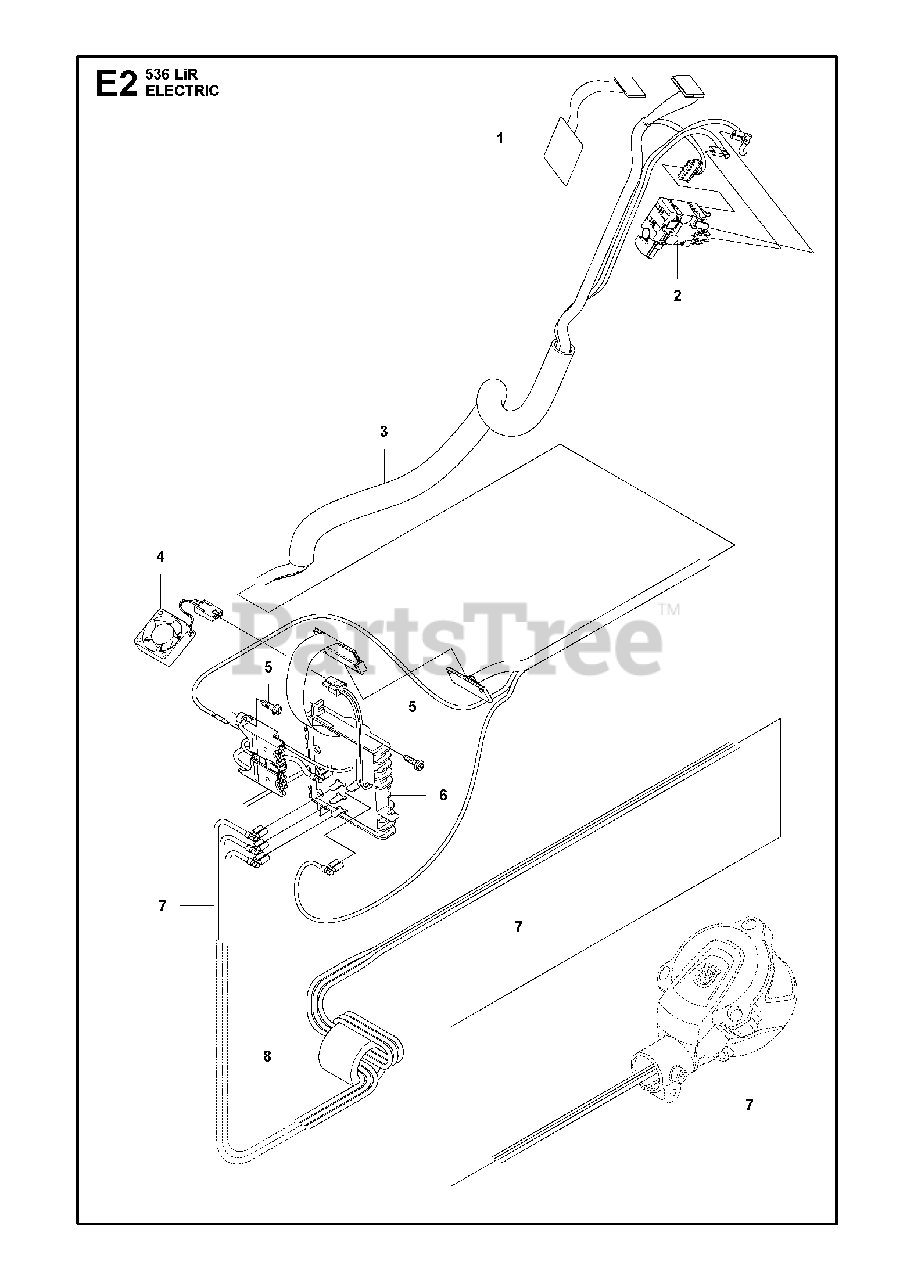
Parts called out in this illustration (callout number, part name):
2	TRIGGER SWITCH
7	MOTOR ASSY
8	FERRITE CORE
